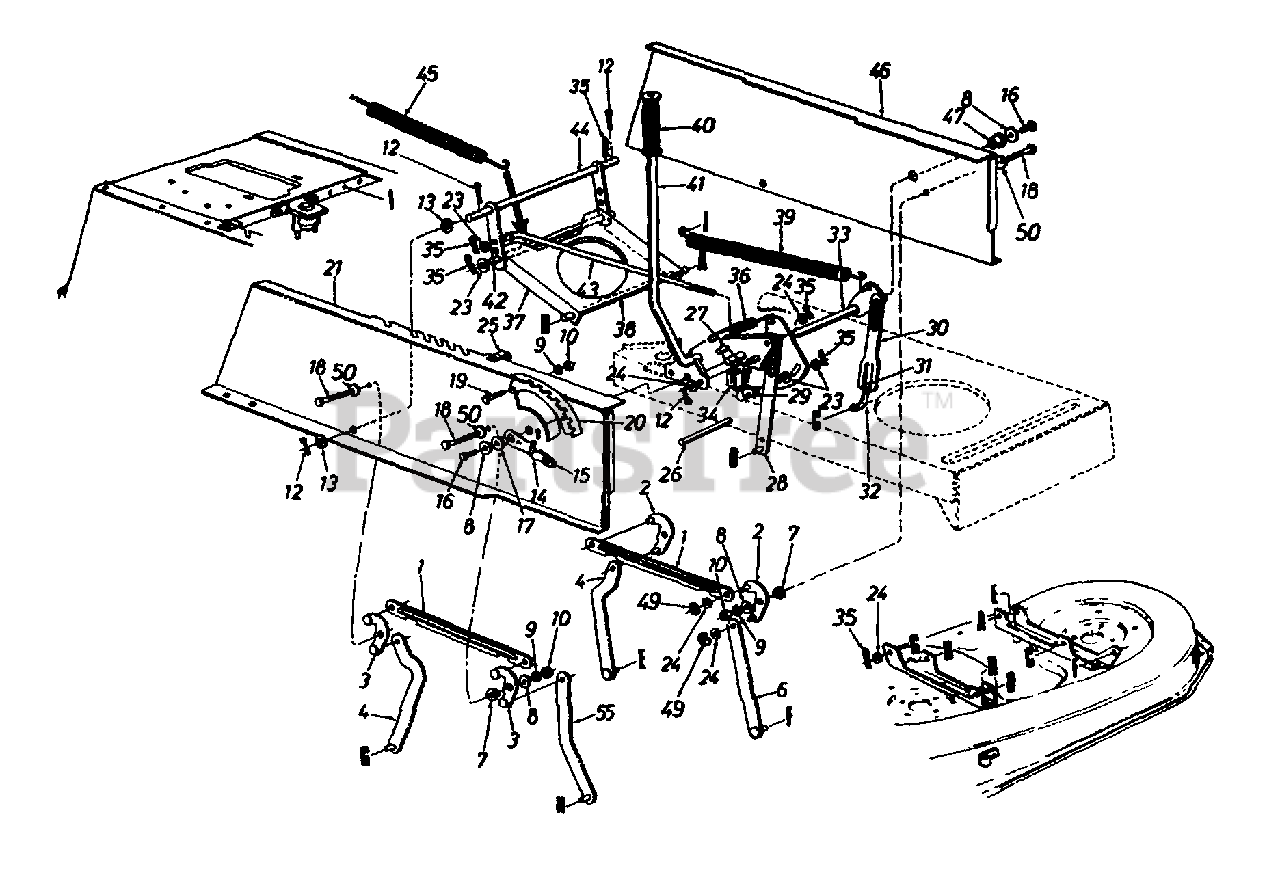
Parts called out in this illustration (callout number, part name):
3	Pivot Link Ass'y. - R.H.
7	Shld. Spacer .318" I.D.
8	Fl-Wash..344" I.D. x .62" O.D.
9	L-Wash. 5/16" I.D.
10	Hex Nut 5/16-18 Thd. - Gr. 5
12	Cotter Pin 1/8" Dia.
13	Fl-Wash. .635" I.D. x 1.0" O.D.
14	Height Adj. Stop Lever Ass'y.
15	Knob
16	Hex Wash. TT-Tap Scr. 5/16-18 x .75" Lg.
17	Flange Brg. .63" I.D.
18	Hex Wash. Hd. Scr. 5/16-18 x .875" Lg.
19	Hex Bolt 5/16-18 x .75" Lg.
20	Index Brkt.
21	Upper Frame - R.H.
23	Fl-Wash. .385" I.D. x .87" O.D.
24	Fl-Wash. .531" I.D. x .93" O.D.
25	Clamp
26	Running Board Rod
27	Hex Wash Hd. Tap Scr.
31	Hex Nut 1/2-20 Thd. (Gr. 5)
32	Lift Link Adjuster
35	Inter. Cotter Pin 3/8" Dia.
36	Extension Spring
39	Extension Spring
40	Grip (Lift Handle)
43	Disengagement Rod
49	"E"-Ring
50	Bell-Wash .325" I.D.
